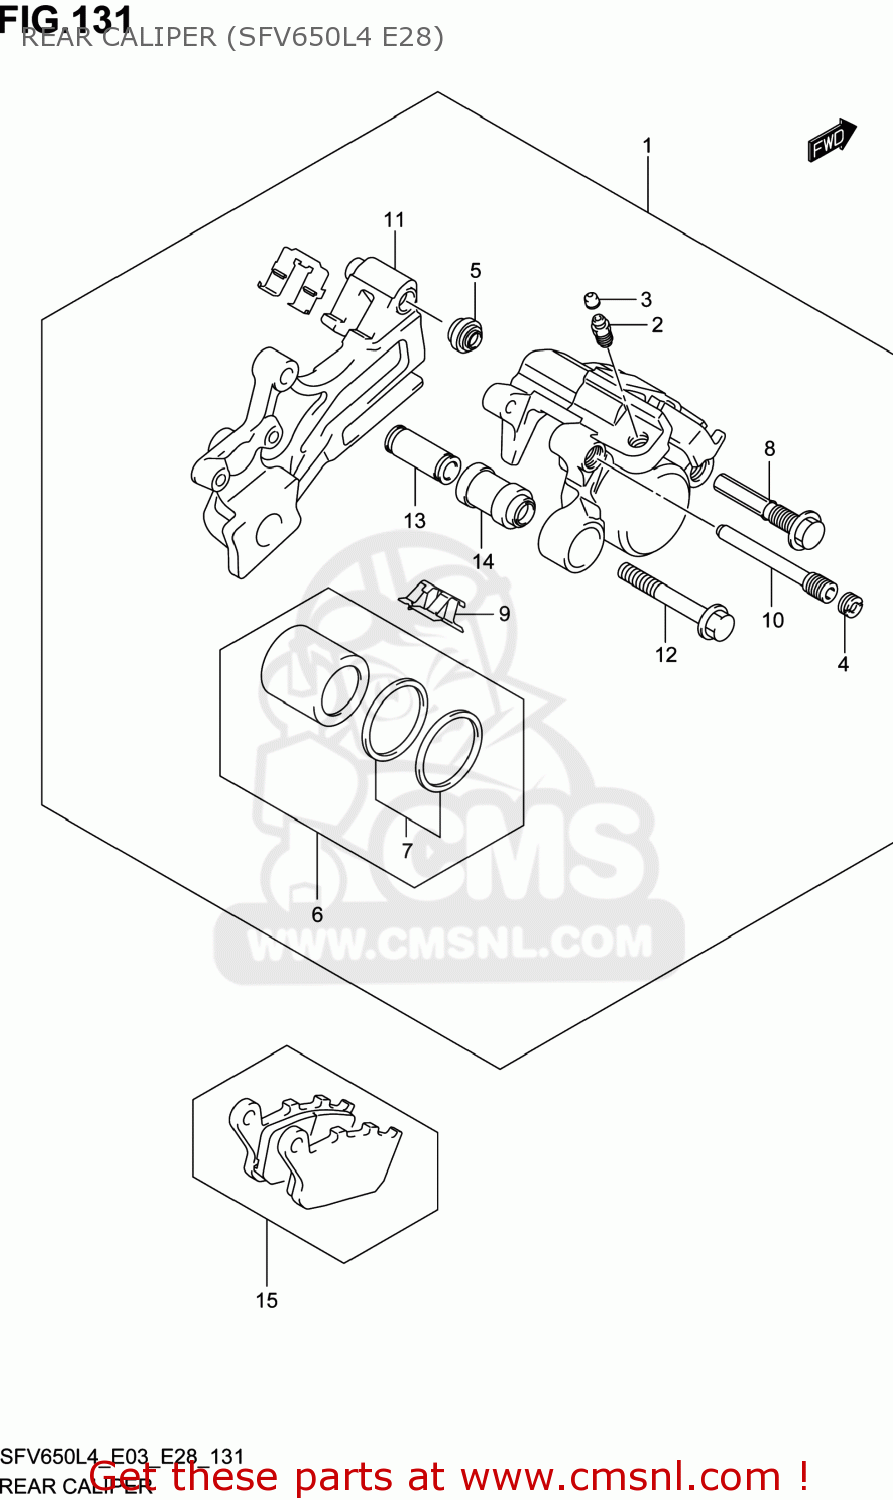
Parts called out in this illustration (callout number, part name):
1	CALIPER ASSY,RR
2	BLEEDER
3	CAP,BLEEDER
4	PLUG,PIN
5	BOOT
6	PISTON SET
7	SEAL SET,PISTON
8	BOLT
9	SPRING,PAD
10	PIN,PAD
11	BRACKET
12	BOLT
13	SLEEVE
14	BOOT,SLEEVE
15	PAD SET (NAS)
